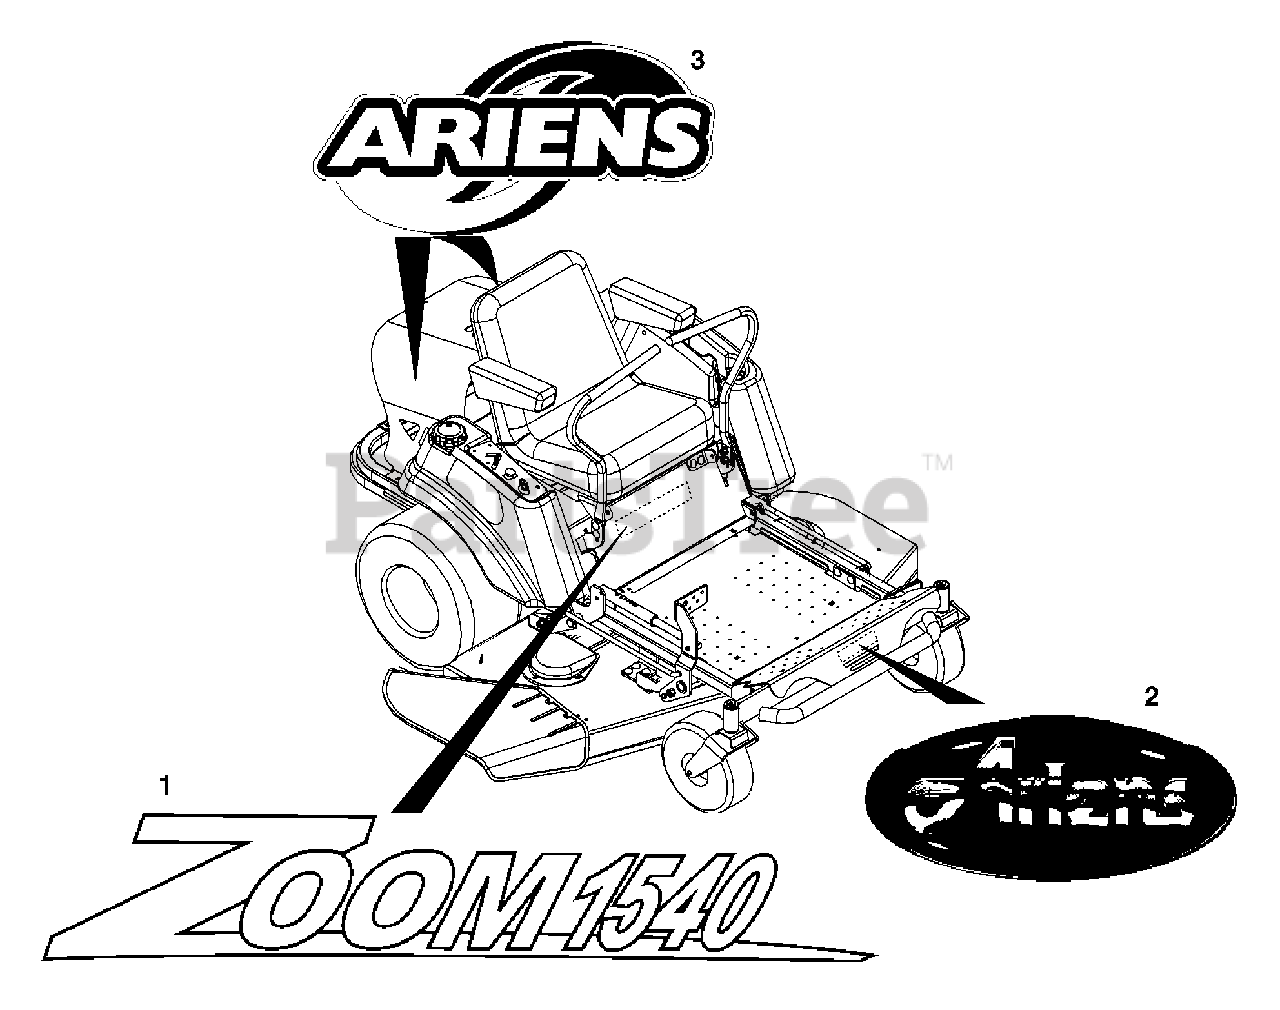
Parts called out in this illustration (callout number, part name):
1	DECAL, ZOOM 1540
2	DECAL-ARIENS JEWEL
3	DECAL ZOOM HOOD
